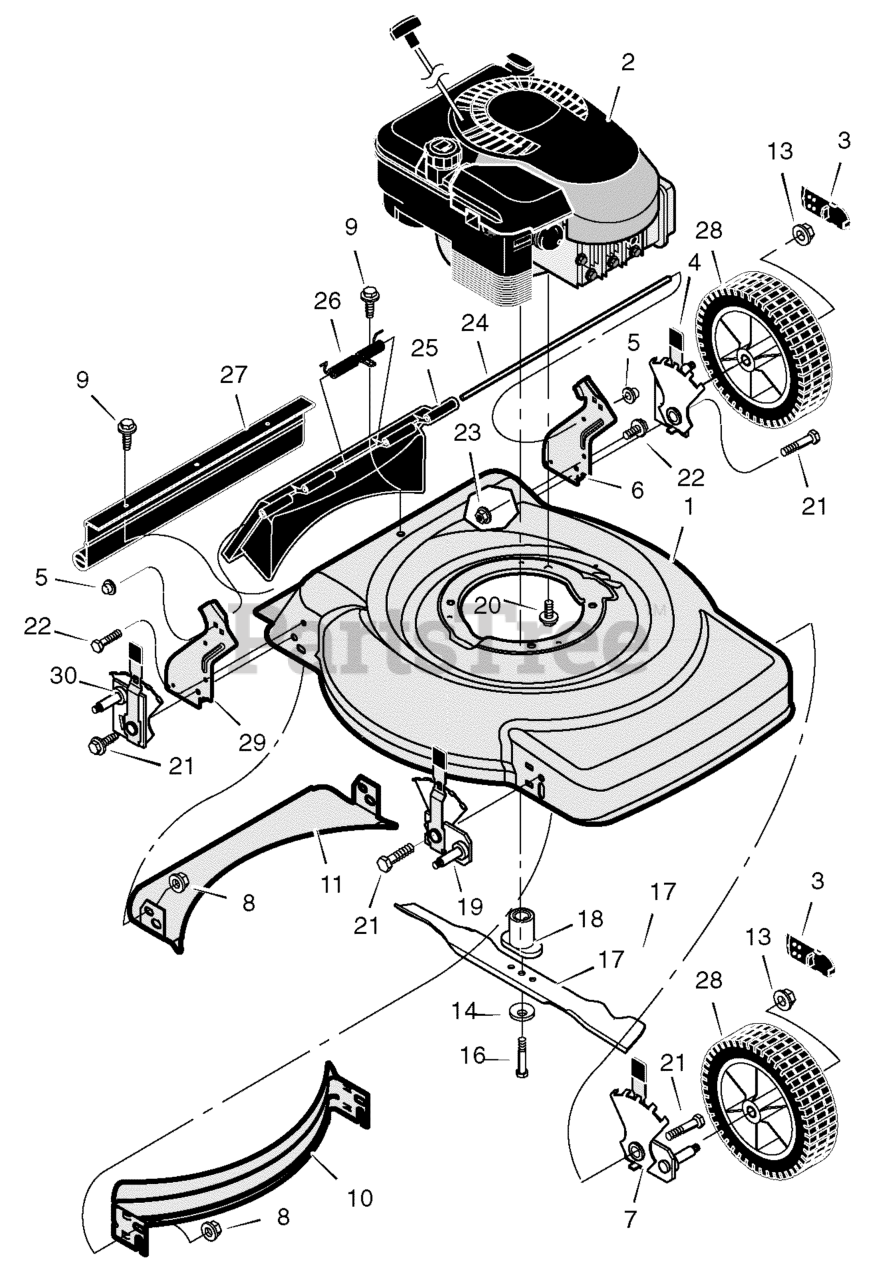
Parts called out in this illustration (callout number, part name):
1	Housing
2	Engine*
3	Cap, Hub (Optional)
4	Adjuster, Left Rear Height
5	Push On Cap
6	Bracket, Left Handle
7	Adjuster, Left Front Height
8	Nut, Flange
10	Baffle, Front
11	Baffle, Rear
13	Nut, Flange
14	Washer, Belleville
18	Adapter, Blade
19	Adjuster, Right Front Height
20	Bolt, Engine
22	Bolt
23	Nut, Flange
24	Rod, Pivot
25	Door, Rear (Black)
26	Spring
27	Guard, Rear
28	Wheel & Tire
29	Bracket, Right Handle
30	Adjuster, Right Rear Height
